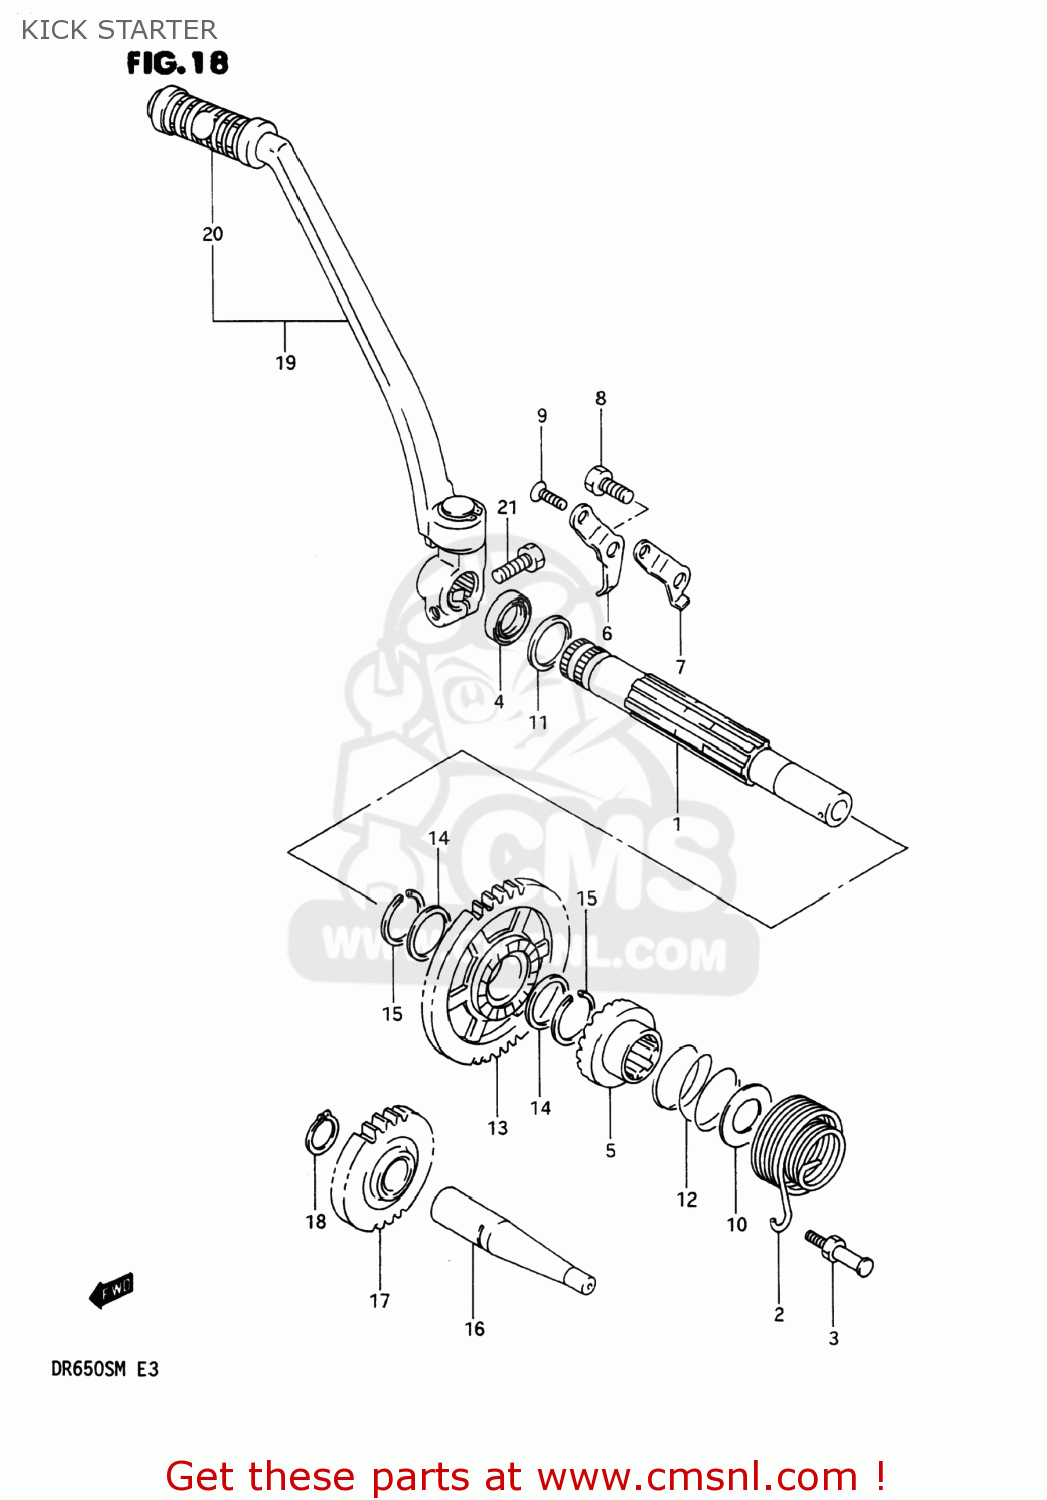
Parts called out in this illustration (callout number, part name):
1	SHAFT,KICK STARTER
2	SPRING
3	BOLT,KICK SHAFT SPRING
4	SEAL,OIL(20X27X6)
5	STARTER,KICK
6	GUIDE,KICK STARTER
7	STOPPER,KICK STARTER
8	BOLT,8X1.25X2
9	SCREW
10	WASHER
11	WASHER,THRUST
12	SPRING
13	GEAR,KICK STARTER DRIVE
14	SHIM
15	CIRCLIP
16	SHAFT,KICK STARTER IDLE
17	GEAR,KICK STARTER IDLE
18	CIRCLIP
19	LEVER ASSEMBLY,KICK STARTER
20	RUBBER,KICK STARTER PEDAL
21	BOLT 8X25
